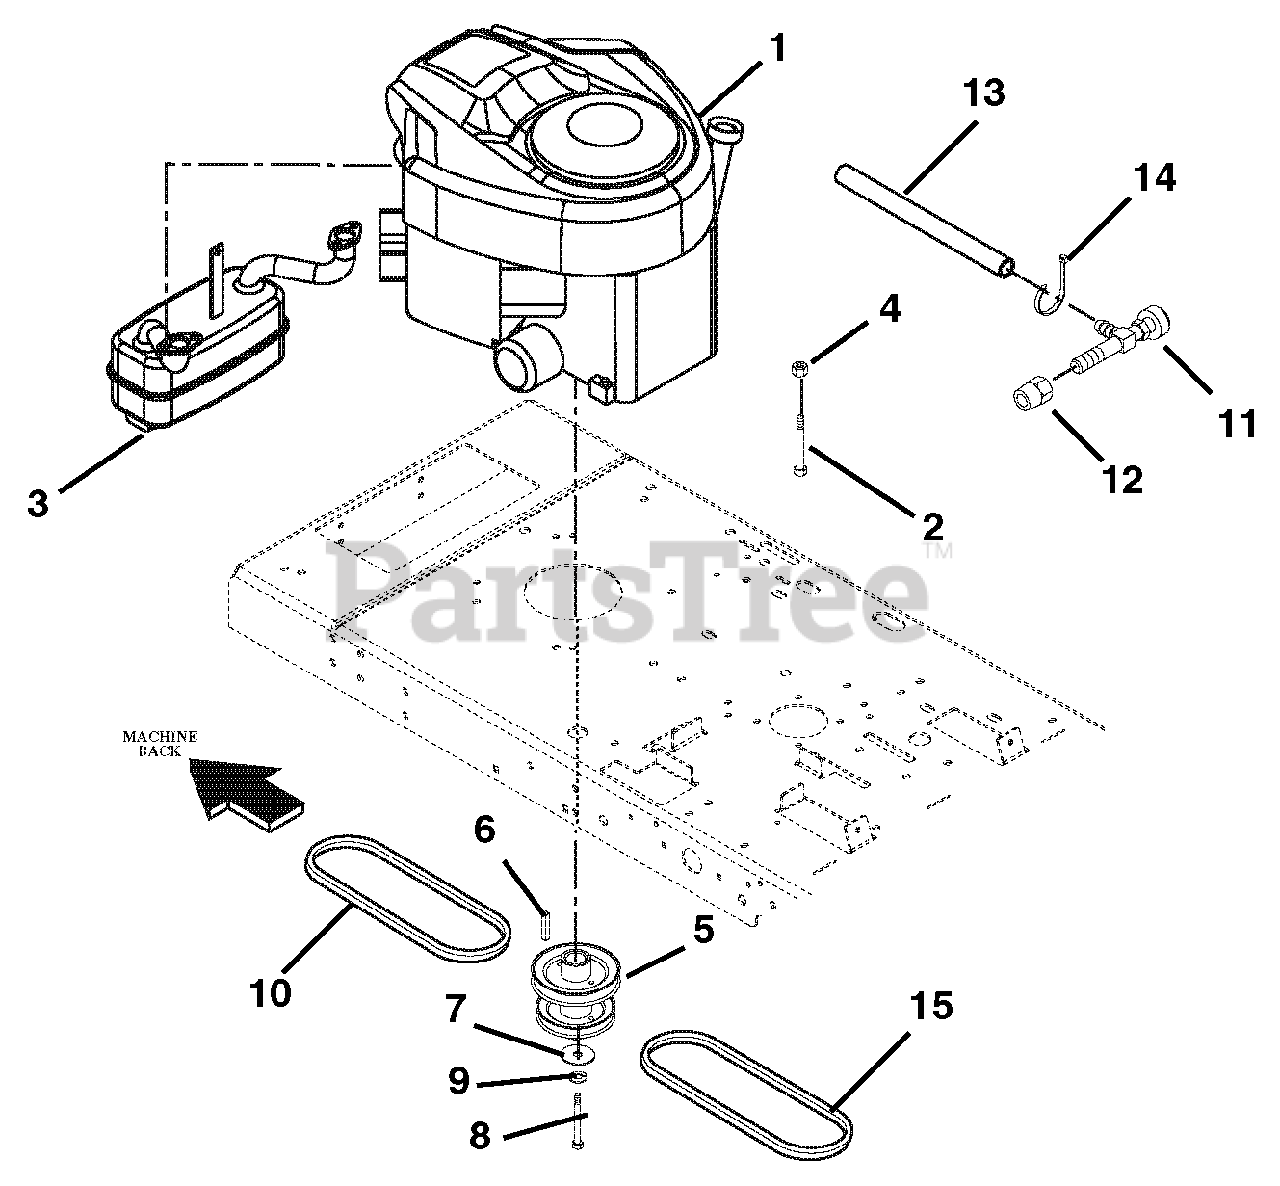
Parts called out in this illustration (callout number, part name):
1	Engine Group - 20HP Gravely
1	Engine Group - 17HP Gravely
2	Screw-Tapping .31-18 x 1.50 Hex Washer Head
3	Muffler Assembly
4	Nut-Locking-Top-Flange .31-18
5	Engine Sheave 4.50
6	Key-Square .25 x 2.50 x .25
7	Washer-Special .469 x 2.000 x .250
8	Bolt-Hex .44-20 x 3.00 Grade 5
9	Washer-Lock .44 x .109
10	V-Belt, Transmission Drive
11	Cock, Oil Drain
12	Adapter, Oil Drain
13	Tube, Oil Drain
14	Cable Tie
15	Belt-5L x 47.1 Engine to Jackshaft
